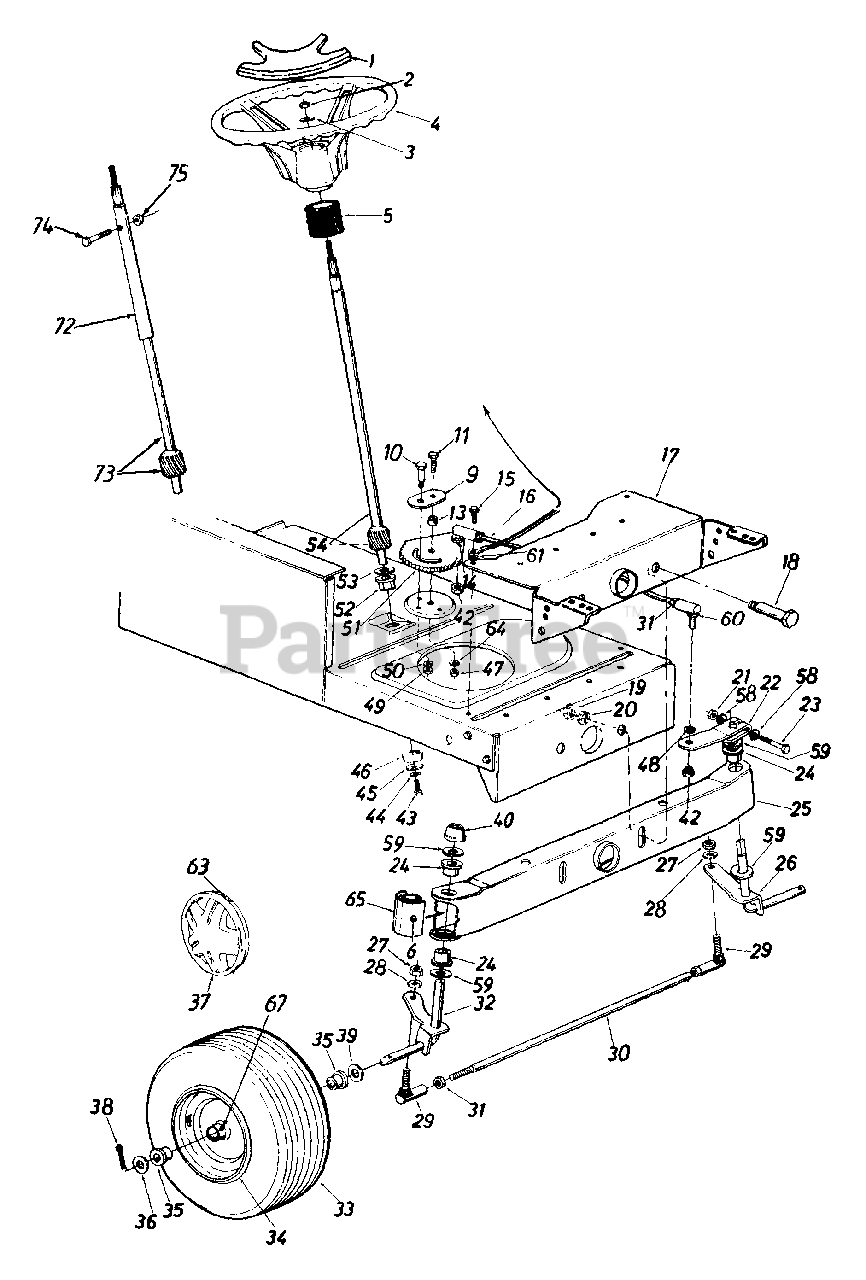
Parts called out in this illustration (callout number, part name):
1	Steering Wheel Cap
2	Hex L-Nut 5/16-24 Thd.
3	Belleville Wash. .345" I.D.
4	Steering Wheel
5	Steering Bellow - 9"
6	Grease Fitting
9	Retainer Plate
10	Shoulder Bolt .437" Dia. x .35" Lg. - 5/16-18 Thd.
11	Hex Bolt 3/8-24 x 1.0" Lg. (Grade 5)
13	Spacer .380" I.D. x .625" O.D. x .227
14	L-Wash. 3/8" I.D. (H.D.)
15	Hex Wash. Hd. Self-Tap Scr.
16	Steering Drag Link
18	Shoulder Bolt .498" Dia. x 2.04" Lg. - 3/8-16 Thd.
19	Flanged L-Nut 3/8-16 Thd.
20	L-Wash. 3/8" I.D.
21	Hex L-Nut 5/16-24 Thd.
22	Steering Arm Front Axle
23	Hex Bolt 5/16-24 x 2.00" Lg. (Grade 5)
24	Hex Flg. Brg. .632 I.D.
26	Front Axle Ass'y. - L.H.
27	Hex Nut 3/8-24 Thd.
28	L-Wash. 3/8" I.D.
29	Ball Joint 3/8-24 Thd.
31	Hex Jam Nut 3/8-24 Thd.
32	Front Axle Ass'y. - R.H.
36	Fl-Wash. .635" I.D. x 1.59" O.D.
37	Front Wheel Hub Cap
38	Cotter Pin 1/8" Dia. x 1.25"
39	Fl-Wash. .640" I.D. x 1.24" O.D.
40	Push Cap 5/8" Dia. Rod
42	Hex Jam Nut 3/8-24 Thd.
43	Hex L-Bolt 5/16-18 x .62"
44	L-Wash. 5/16" I.D.
45	Fl-Wash. .33" I.D. x 1.25" O.D.
46	Spacer (Plastic)
47	Hex Cent. L-Nut 3/8-24 Thd.
48	L-Wash. 3/8" I.D.
49	Hex Cent. L-Nut 5/16-18 Thd.
50	L-Wash. 5/16" I.D.
51	Steering Gear Segment
52	Hex . Flg. Brg..634 I.D.
53	Fl-Wash. (Hardened)
54	Steering Shaft
58	Wave-Wash. .32" I.D. x .62" O.D.
59	Fl-Wash. (Hardened)
60	Drag Link Ball Joint 3/8-24 Thd.
61	Ext. L-Wash. 5/16" I.D.
63	Spring Clip
64	Bell-Wash. .39" I.D. x 1.38" O.D.
65	Pivot Bar End Cap
67	Grease Fitting
72	Upper Steering Shaft
73	Lower Steering Shaft
74	Hex Bolt 1/4-20 x 1.25" Lg.
75	Hex L-Nut 1/4-20 Thd.
